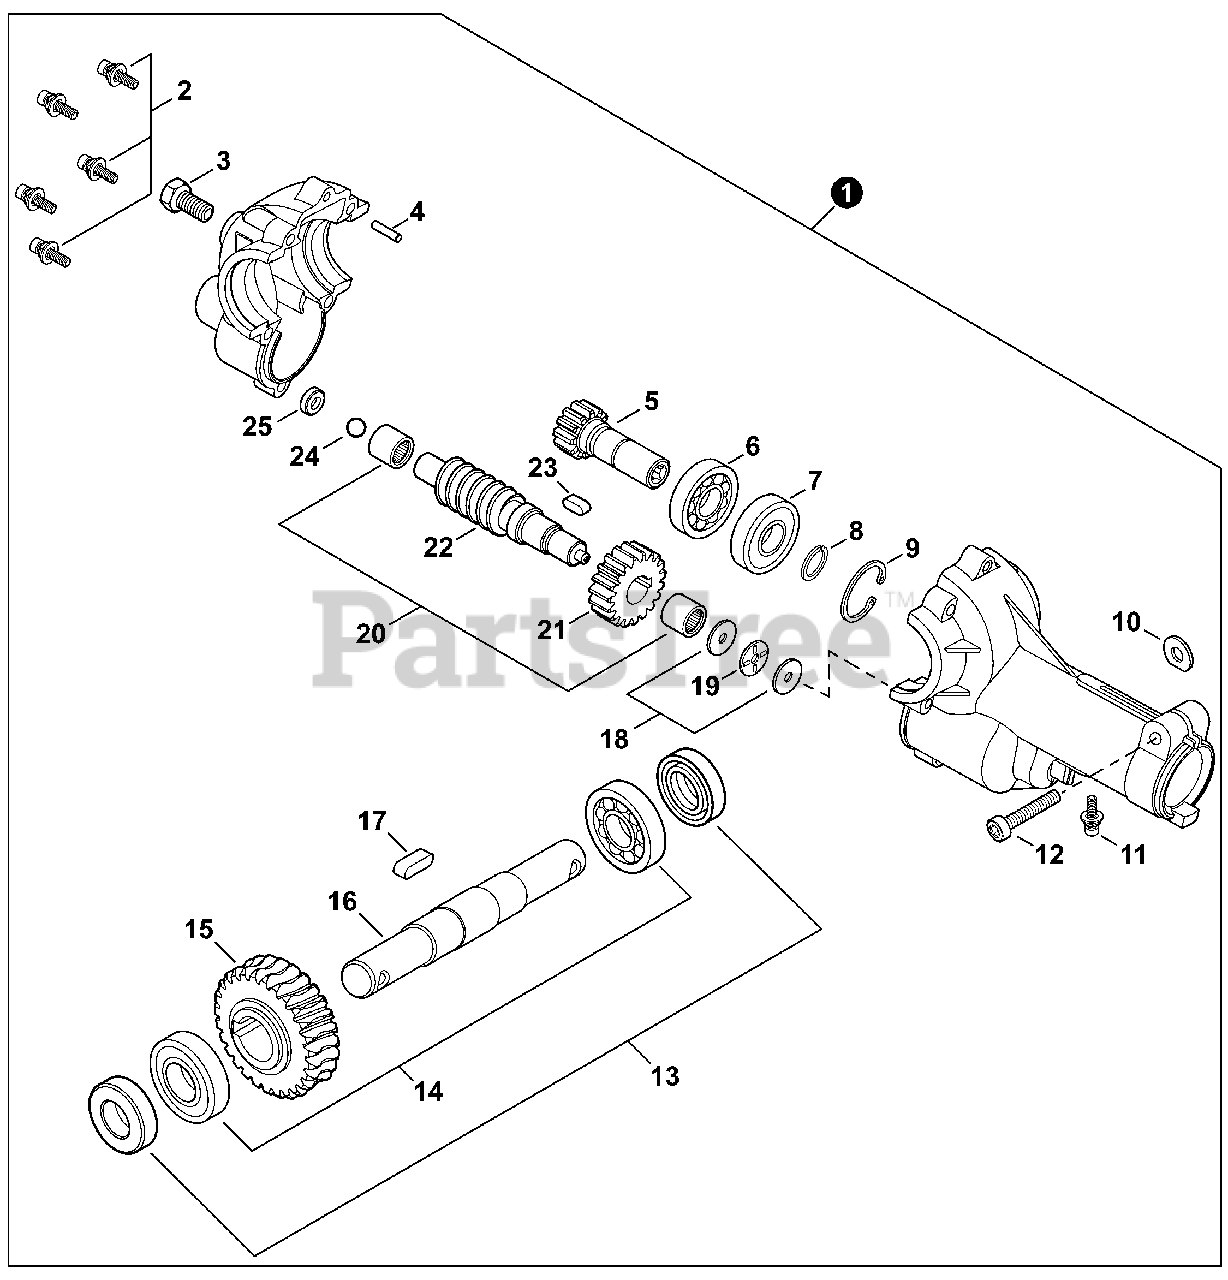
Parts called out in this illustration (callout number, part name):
1	GEAR CASE ASSY
2	BOLT 5×20
3	BOLT 8×10
4	PIN, LOCATING 4×20
5	GEAR, SPUR 12 TOOTH
6	BEARING, BALL 6901
7	BEARING, BALL 6901
8	RING, SNAP Ø12
9	RING, RETAINING Ø24
10	D-WASHER
11	BOLT 5×12
12	BOLT 6×30
13	SEAL, OIL 17
14	BEARING, BALL 6003
15	GEAR, WORM WHEEL
16	SHAFT, GEAR
17	KEY, WOODRUFF
19	BEARING, THRUST
20	BEARING, NEEDLE 10
21	GEAR, SPUR 19 TOOTH
22	GEAR, WORM
23	KEY, WOODRUFF
